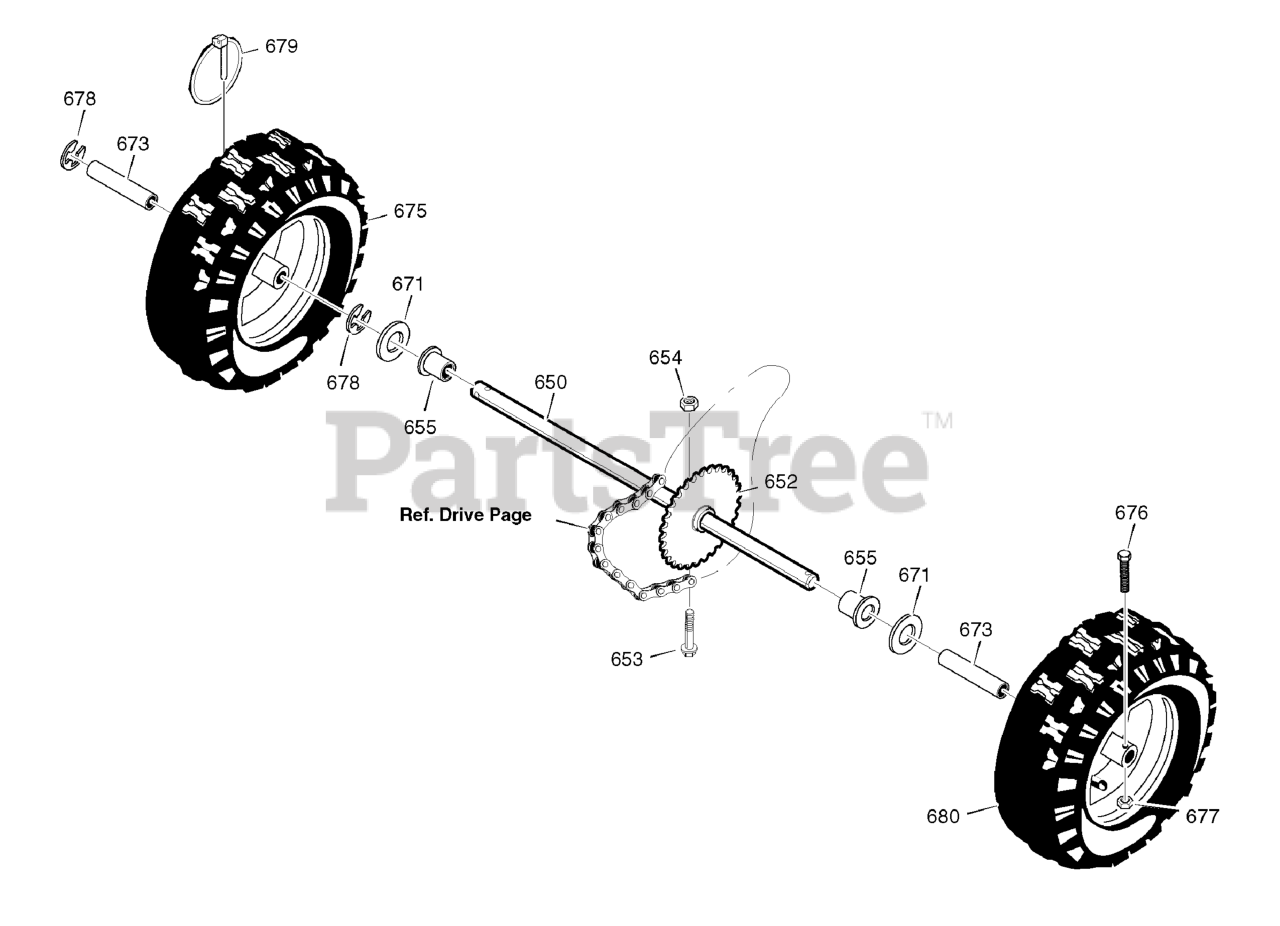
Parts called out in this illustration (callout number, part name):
650	SHAFT, AXLE
652	SPRKT & HUB
653	SCREW, 1/4-20 x 1.75
654	NUT, 1/4-20 HEX NYLOCK
655	BEARING, AXLE
671	FLATWASHER
673	BUSHING, WHEEL
675	TIRE & RIM, RIGHT
676	SCREW, 1/4-20X1.75 HH
677	NUT, 1/4-20 HEX NYLOCK
678	RING, RET
679	PIN, KLIK .25 X 1.38 DIA
680	TIRE & RIM, LEFT
